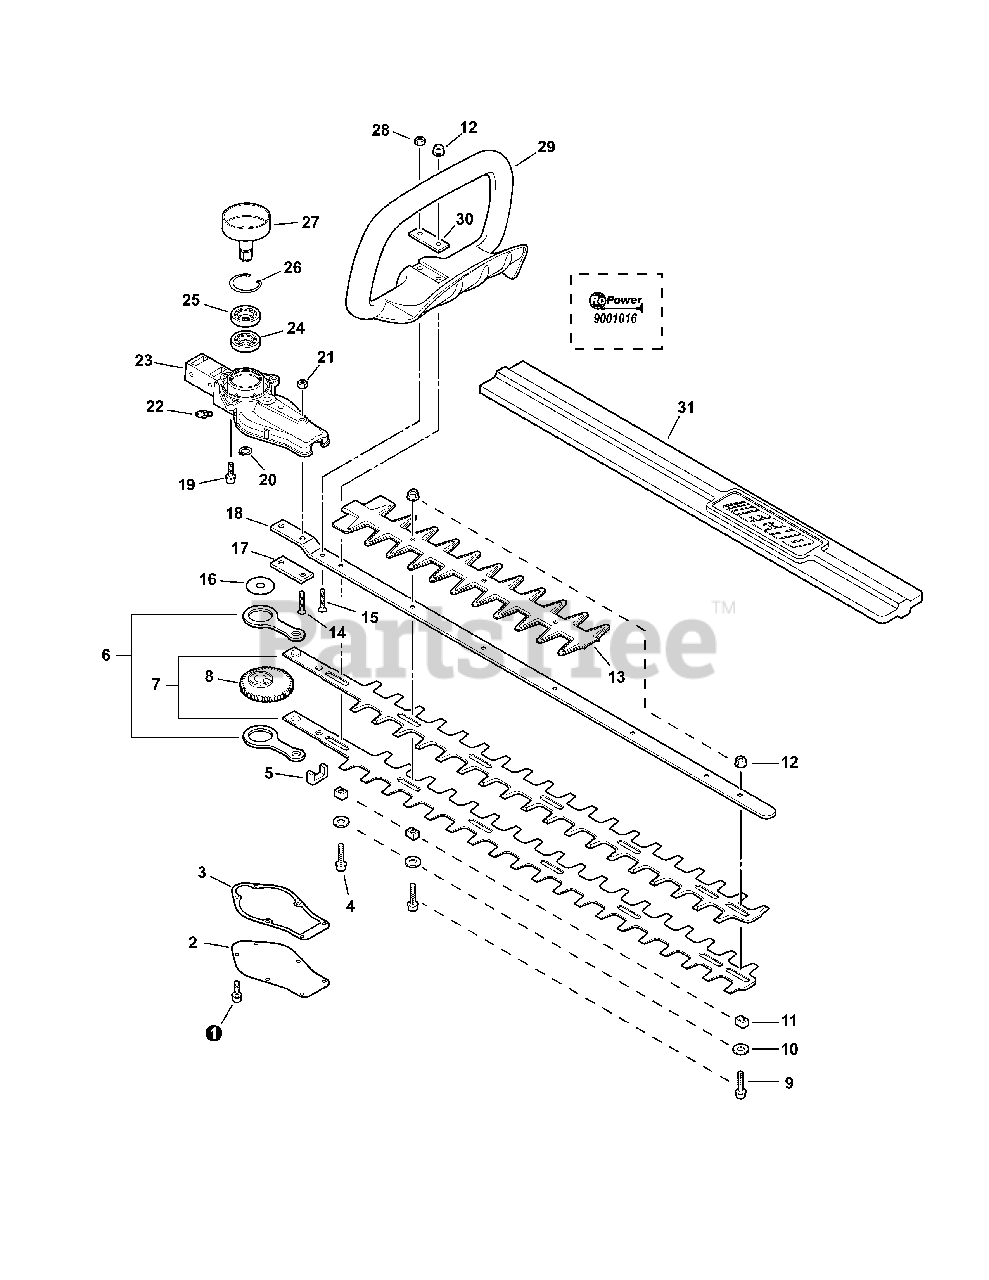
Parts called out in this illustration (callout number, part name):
1	BOLT 4×10
2	COVER, GEAR CASE
3	GASKET, GEAR CASE
4	BOLT 5×40
6	ROD, CONNECTING
7	CUTTER 24"
9	BOLT 5×20
10	WASHER 5
11	GUIDE, BLADE 5
12	NUT, FLANGE M5
13	GUARD, CUTTER BLADE
14	SCREW 6×25
15	SCREW 5×30
17	PLATE, EYE
18	SUPPORT, BLADE 24"
19	BOLT 5×20
20	RING, SNAP 14
21	NUT, HEX M6
22	FITTING, GREASE
23	GEAR CASE ASSY
24	BEARING, BALL 6202
25	BEARING, BALL 6202
26	RING, SNAP 35
27	DRUM, CLUTCH
28	NUT, LOCK M5
29	HANDLE, FRONT
30	PLATE, EYE
31	SCABBARD
32	CUTTING HEAD KIT
